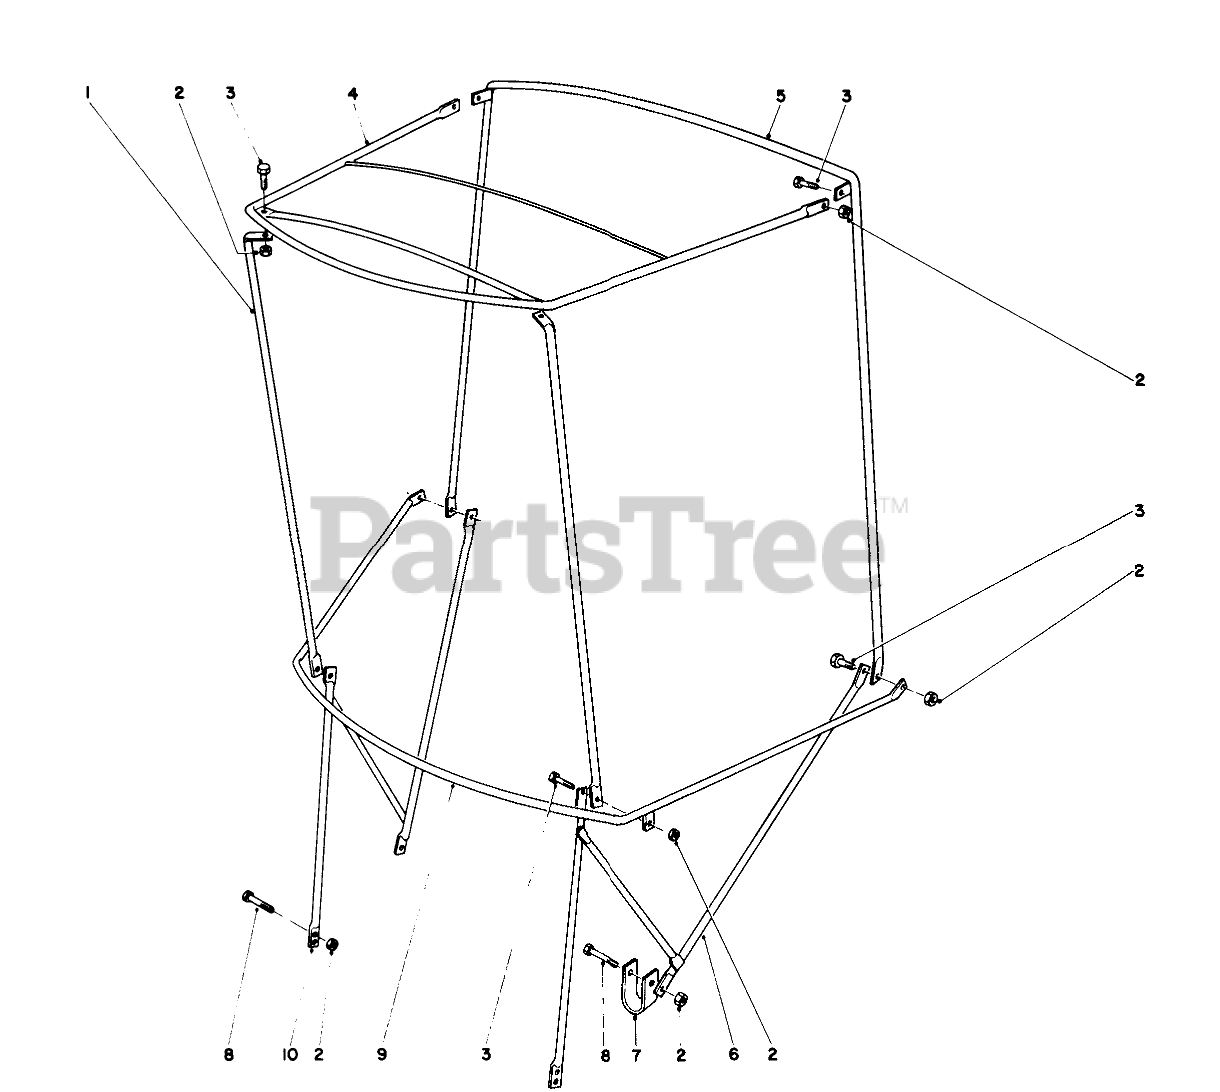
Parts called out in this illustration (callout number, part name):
3	SCREW-HH
4	FRAME-TOP
5	BOW-VERTICAL, REAR
6	ATTACHING BRKT L
7	U CLAMP
8	SCREW-HH
9	BOW-CURVED
10	ATTACHING BRKT R
